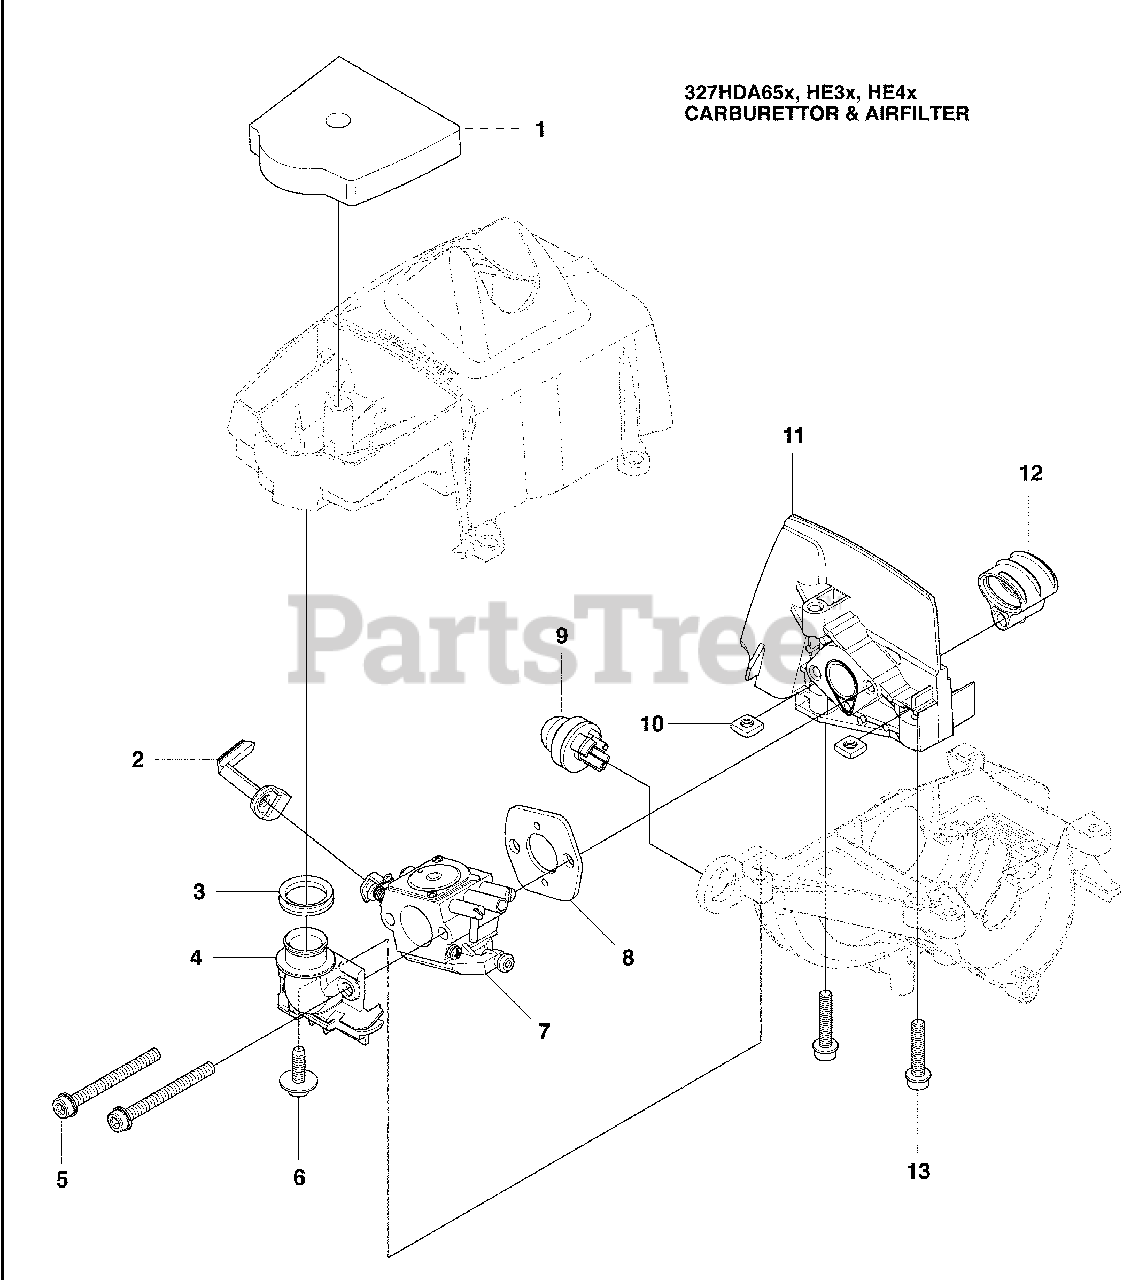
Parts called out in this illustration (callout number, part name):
1	Air Filter
2	Choke Control Lever
7	Carburetor
8	Carburetor Gasket
9	Air Purge Bulb
10	Square Nut
